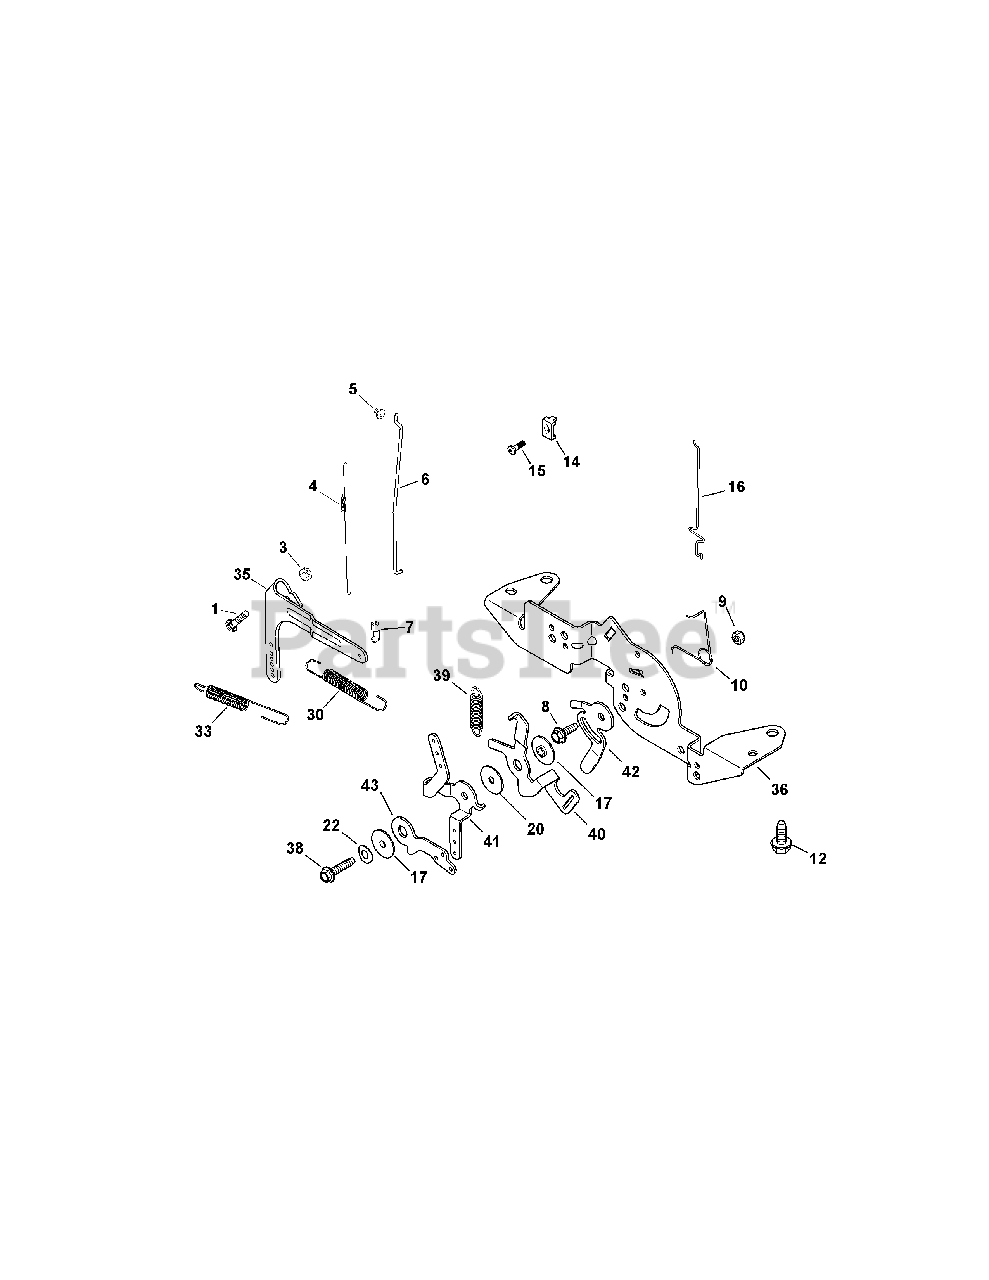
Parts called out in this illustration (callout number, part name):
1	Rd. Hd. Sq. Neck Bolt, M6 X 1.0 X 25
3	Flg. Nut, M6 X 1.0
4	Linkage Spring
5	Linkage Retaining Bushing
6	Throttle Linkage
7	Throttle Linkage Bushing
8	Flg. Thd. Frm. Screw, M5 X 0.8 X 16
9	Lock Nut, M5 X .8
10	Choke Return Spring
12	Flg. Thd. Frm. Screw, M6 X 1.0 X 16
14	Cable Clamp
15	Lbd. Thd. Frm. Screw, M5 X 0.8 X 16
16	Choke Linkage
17	Control Assembly Spacer
20	Flat Washer. 5.5mm
22	Spring Washer, 1/4
30	Governor Spring
33	Governor Spring
35	Governor Lever
36	Control Bracket
38	Thd. Frm. Screw, M5 X 0.8 X 25mm
39	Speed Control Spring
40	Governor Spring Lever
41	Speed Control Lever
42	Speed Setting Lever
